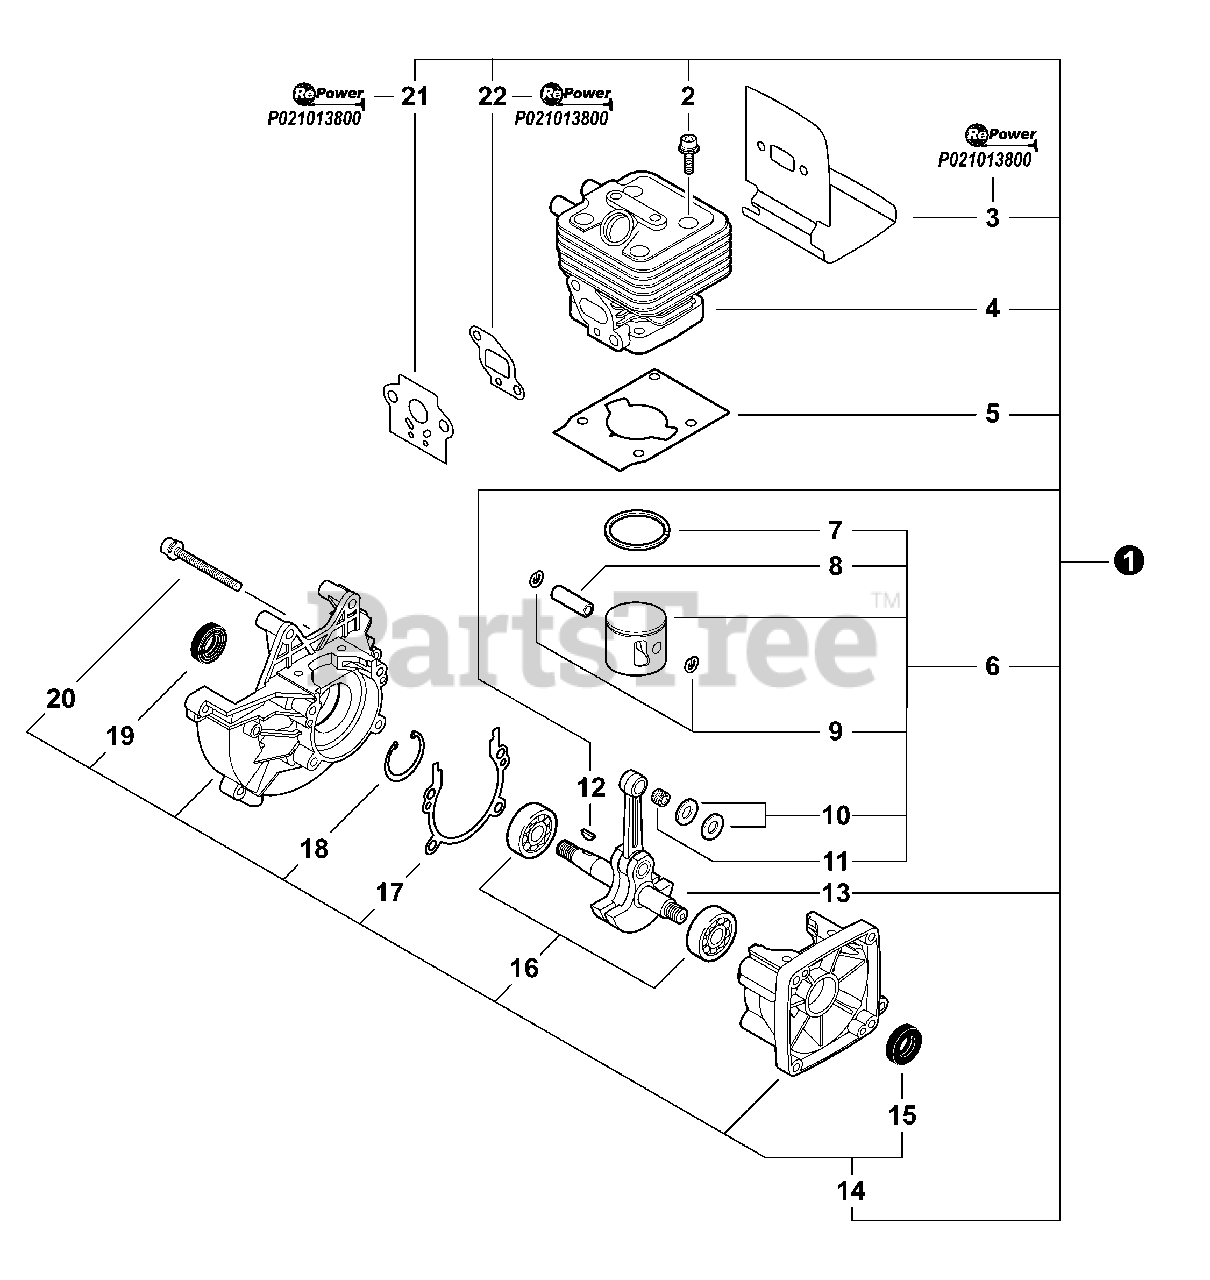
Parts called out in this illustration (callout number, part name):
1	SHORT BLOCK -- SB1091
2	SCREW - 5×25
3	SHIELD, EXHAUST
4	CYLINDER
5	GASKET, CYLINDER
6	PISTON KIT
7	RING, PISTON
8	PIN, PISTON
9	RING, RETAINING
10	SPACER, PISTON
11	BEARING, NEEDLE
12	KEY, WOODRUFF
13	CRANKSHAFT ASY
14	CRANKCASE KIT
15	SEAL, OIL - 12
16	BEARING, BALL - 6201
17	GASKET, CRANKCASE
18	RING, RETAINING - 32
19	SEAL, OIL
20	SCREW - 5×28
21	GASKET, INTAKE
22	GASKET, INTAKE
